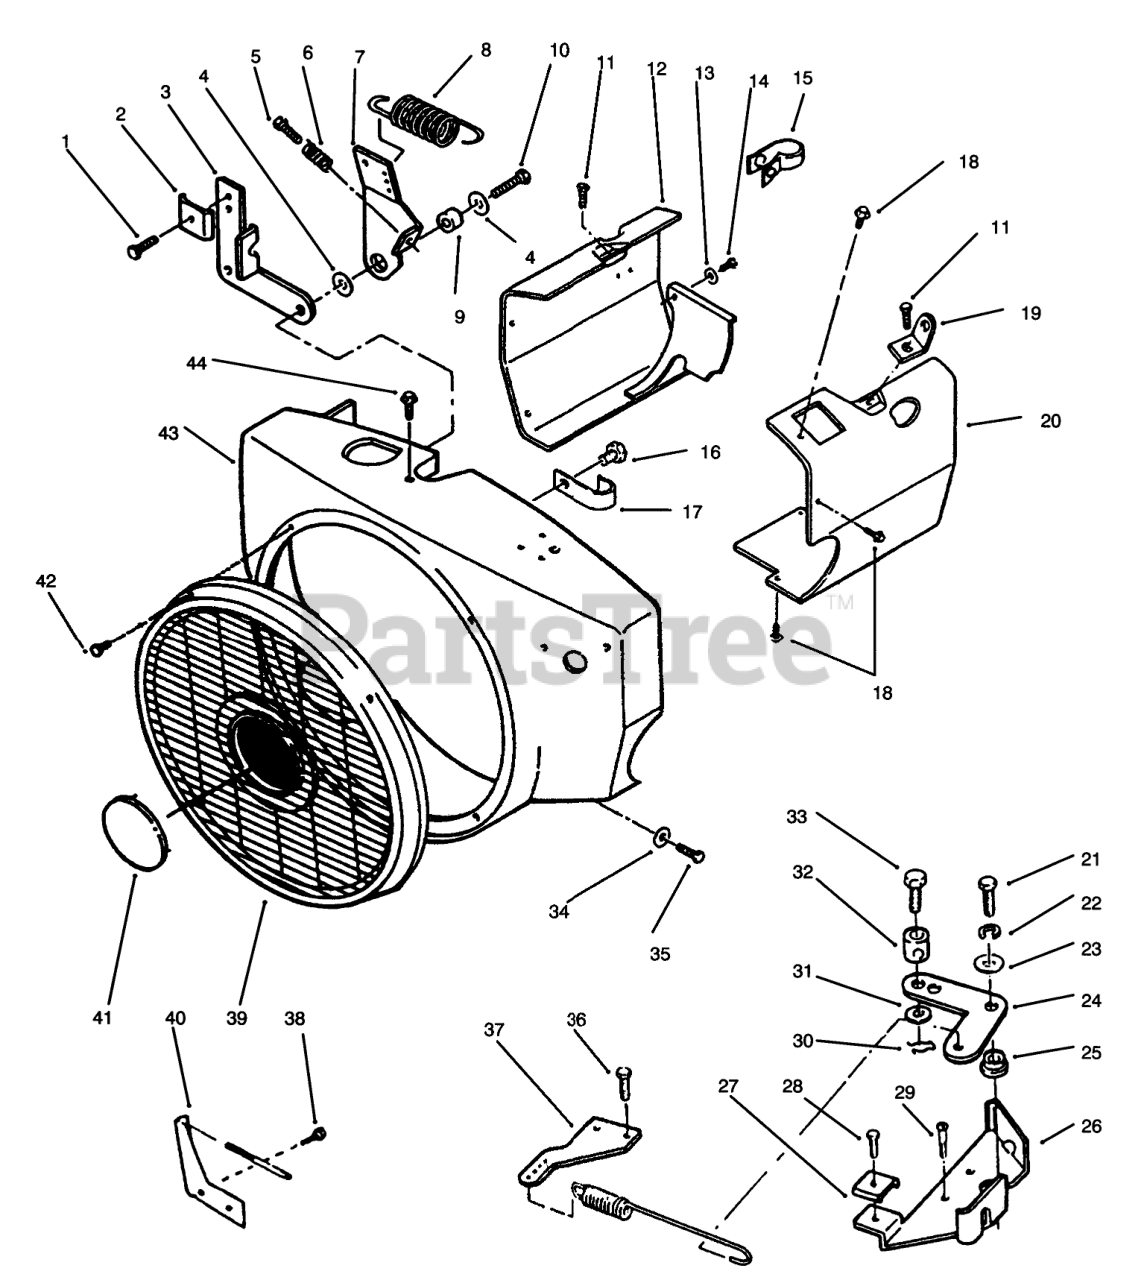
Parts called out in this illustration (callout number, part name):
1	SCREW-TAPPING
3	Bracket
4	WASHER-FLAT
5	SCREW-TAP
6	SPRING
7	GOVERNOR-CONT ARM
8	SPRING
9	BUSHING
11	SCREW-HWH
12	LH AIR CYLINDER HSG
13	WASHER-FLAT
14	SCREW-HH
15	Clamp
16	SCREW-HWH
17	CLIP-WIRE
18	SCREW-HWH
19	BRACKET-LIFTING
20	RH AIR CYLINDER HSG
21	SCREW - CAP HEX HEAD
22	WASHER-LOCK, SPRING
23	WASHER-FLAT
24	Governor Control Arm
25	BUSHING-GOV CONTROL
26	BRKT-GOVERNOR CONTRL
28	SCREW-HWH
29	HEX HD CAP SCREW
30	PIN-COTTER
31	Washer
32	BUSHING
33	SCREW
34	WASHER-FLAT
35	SCREW-HH
36	SCREW-TAPPING PAN HD
37	ADAPTER-GOV ARM
38	SCREW-HWH
39	GUARD-STATIONARY
40	BRACKET
41	NAME-PLATE TORO LOGO
42	SCREW-PAN HEAD
43	BLOWER-HOUSING
44	HEX HD CAPSCREW
